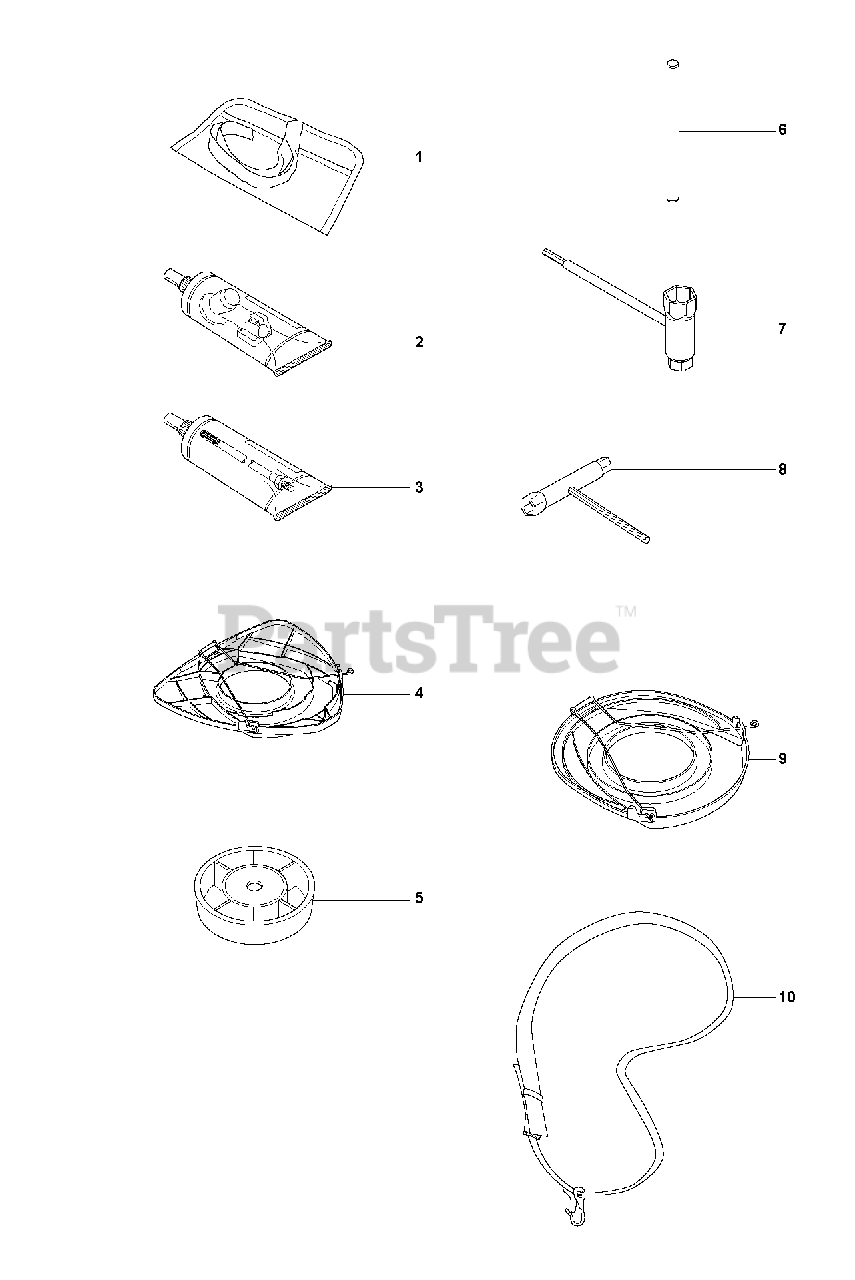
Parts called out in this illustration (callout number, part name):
4	TRANSPORT GUARD
5	SUPPORT CUP
6	LOCKING PIN
7	RP COMBI TOOL
8	COMB.TOOL 8-10-14
9	BLADE GUARD TRANSPORT
10	STRAP
10	SHOULDER STRAP WITH SIGN
